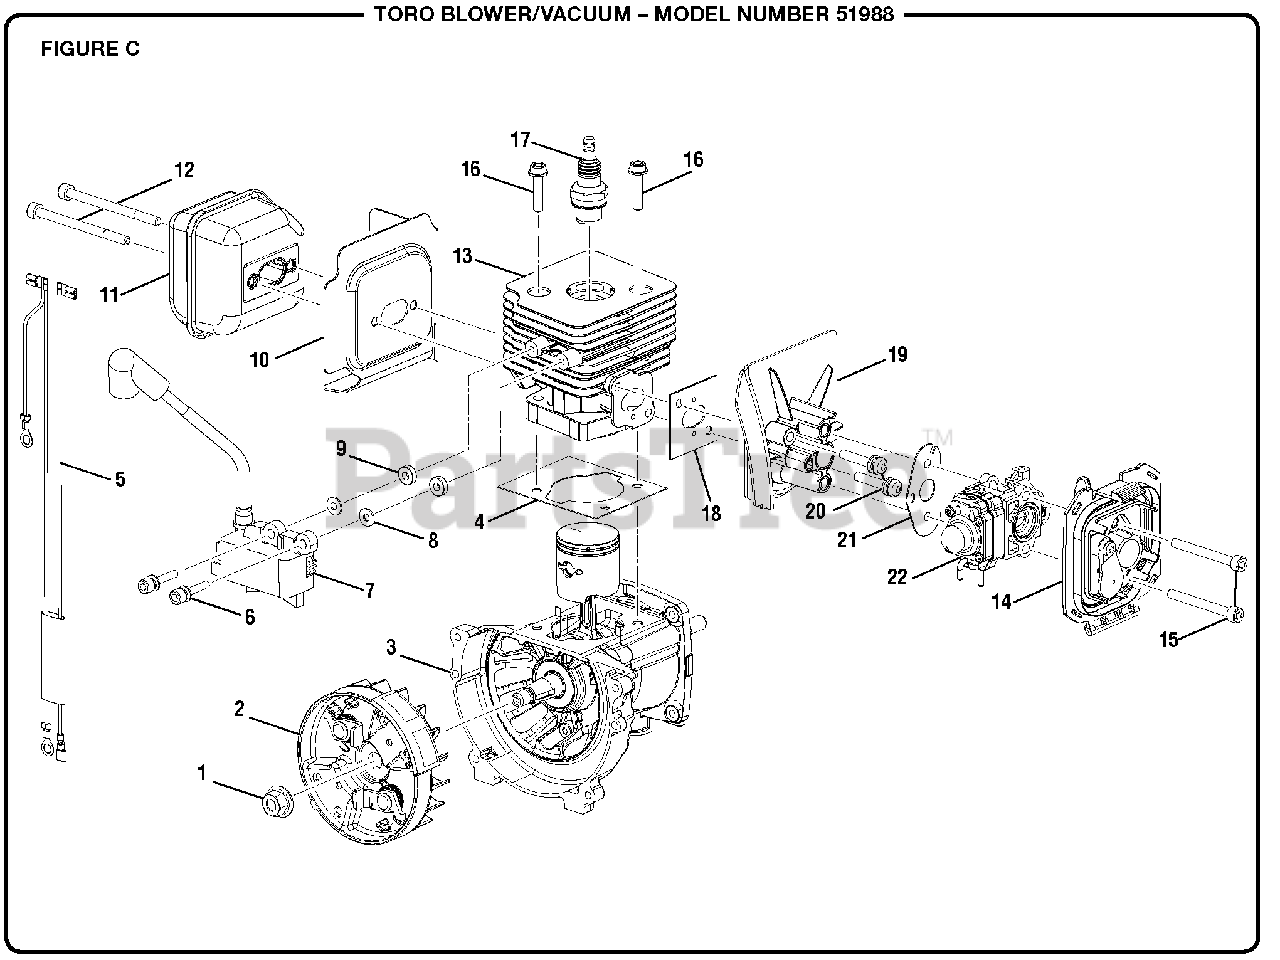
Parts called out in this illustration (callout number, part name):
1	Nut (M8)
2	Flywheel Assembly
3	Crankcase and Piston Assembly
5	Wire Harness
6	Screw (M4 x 22 mm, Torx T20)
7	Ignition Module
8	Washer (4.2ID x 10OD x 1t)
10	Muffler Gasket
11	Muffler Assembly
12	Screw (M5 x 65 mm, Torx T25)
14	Air Box Cover Base Assembly
15	Screw (M5 x 45 mm, Torx T25)
16	Screw (M5 x 22 mm)
17	Spark Plug (RCJ6Y)
18	Cylinder Gasket
19	Heat Sink
20	Screw (M5 x 30 mm, Torx T25)
21	Carburetor Gasket
22	Carburetor Assembly
